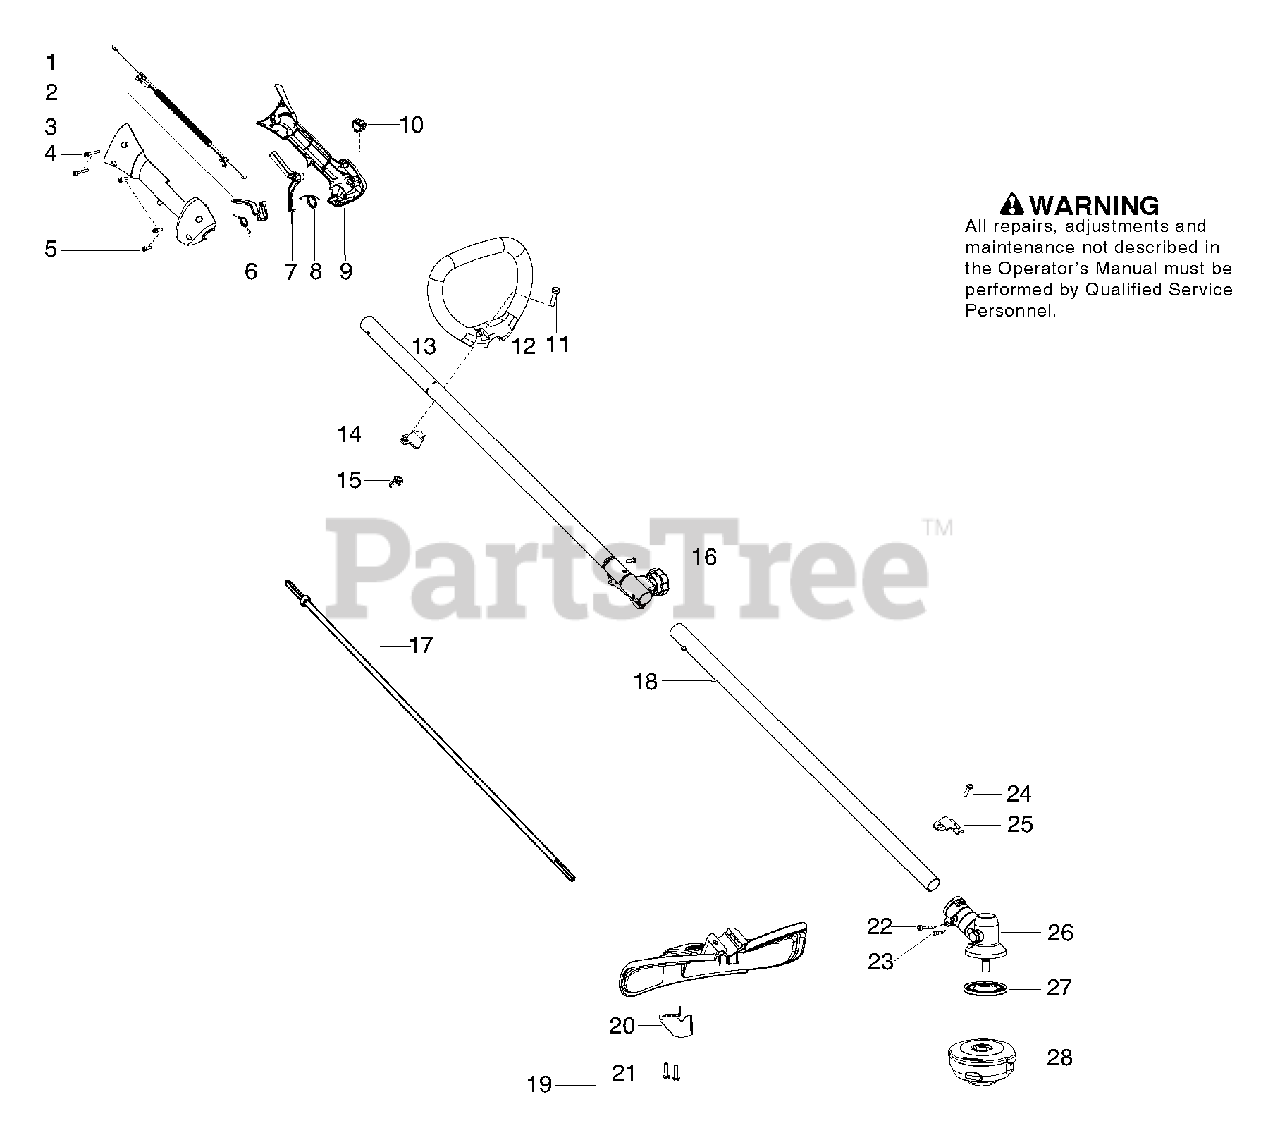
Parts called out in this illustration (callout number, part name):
1	Assy-Cable/Wire Harness
3	Housing-Throttle (RH)
6	Spring-Trigger
7	Lockout-Throttle
8	Spring-Lockout
9	Housing-Throttle (LH)
10	Kit-Switch
12	Handle-Assist
13	Kit-Driveshaft Upper
14	Clamp-Handle
15	Wingnut
17	Flex-Lower
18	Kit-Lower Shaft
19	Kit-Shield
20	Limiter-Line
25	Bracket-Shield
26	Assy-Gearbox
27	Driver Disc
28	Assy-T25 Cutting Head
